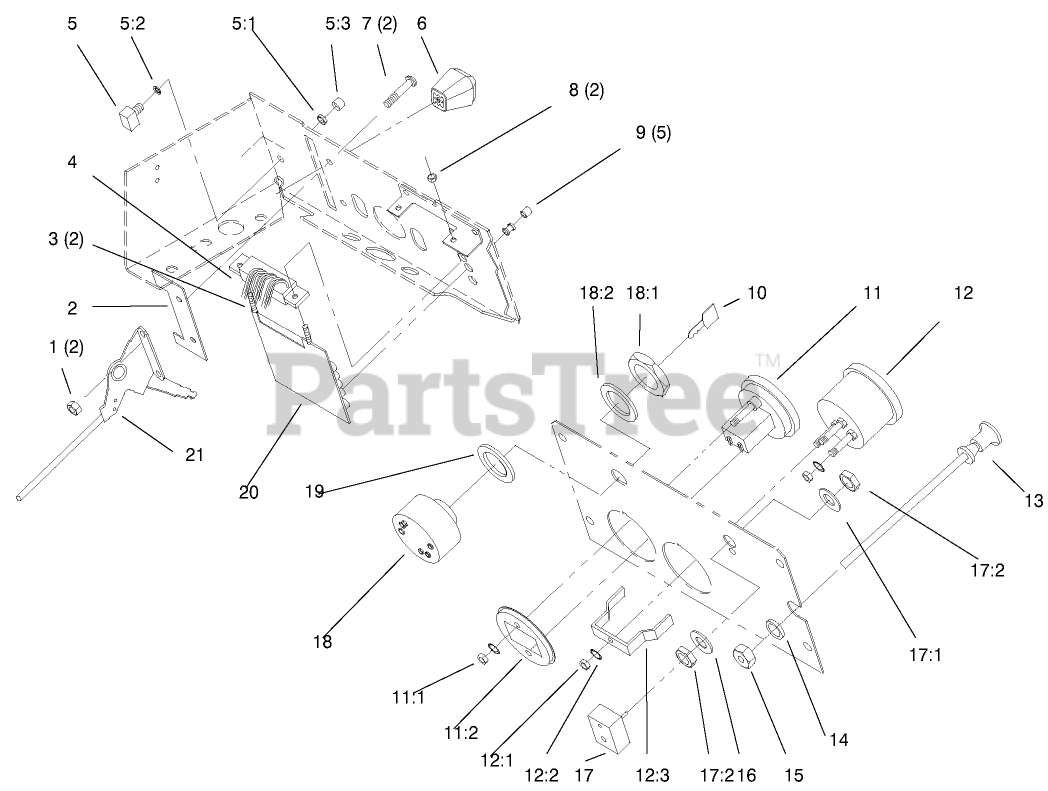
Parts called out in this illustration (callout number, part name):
2	Washer
3	Screw
4	P.C.-BOARD HARNESS
5	SWITCH-PUSH BUTTON
7	SCREW-PPH
8	NUT-HEX, NYL INS
9	ASSY LENS & BUSHING
10	KEY-IGNITION
11	VOLTMETER
13	CONTROL CHOKE
14	WASHER-FLAT
15	NUT-HEX PALNUT
16	WASHER
17	SWITCH-LIGHTS
18	KEY SWITCH ASM
19	WASHER
21	CONTROL-THROTTLE
